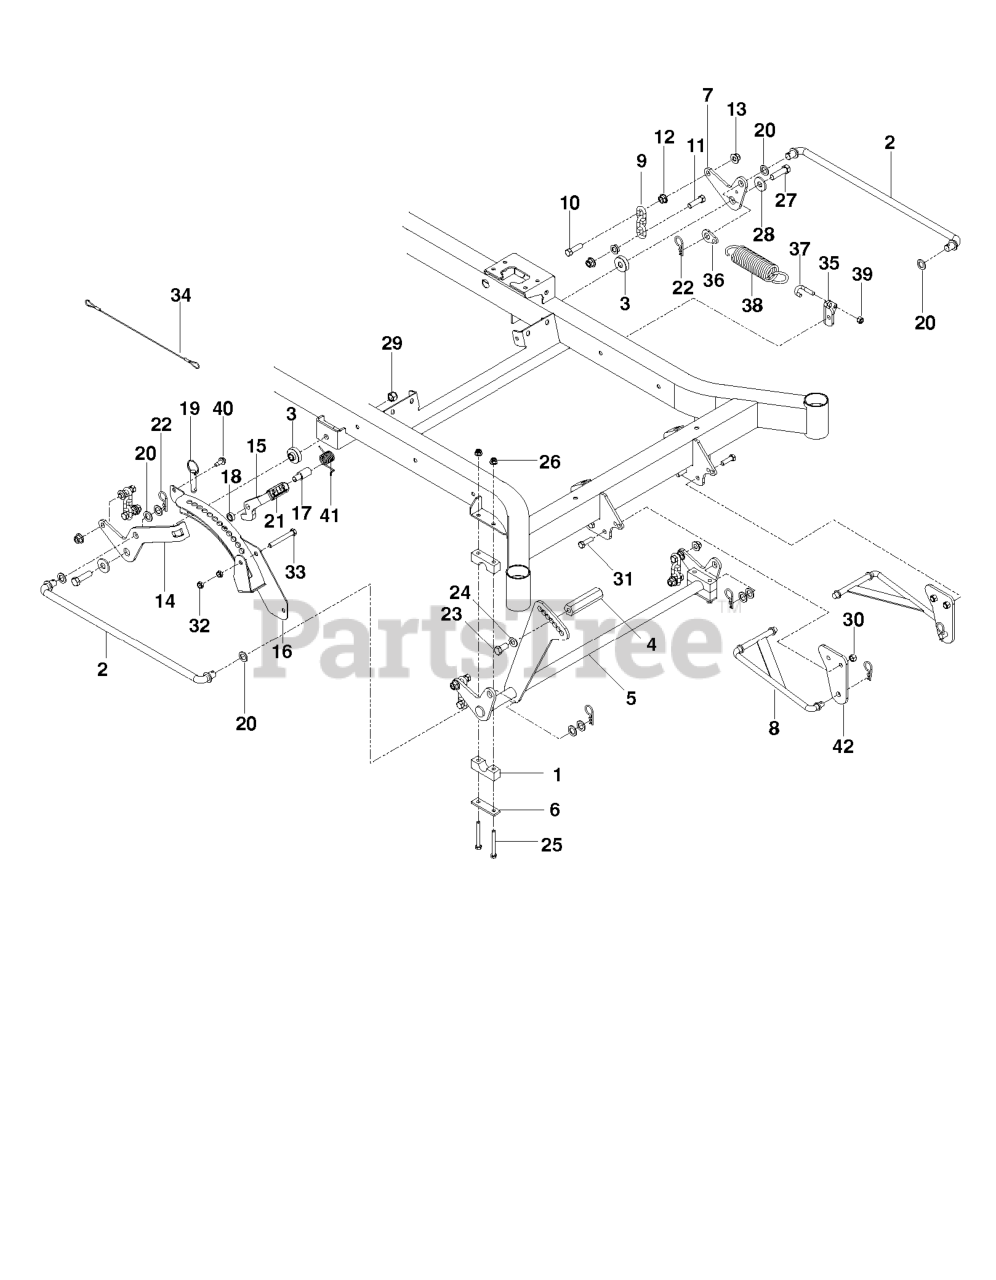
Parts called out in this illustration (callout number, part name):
1	PILLOW BLOCK
2	CROSS LINK
3	IDLER SPACER
4	PEDAL, FOOT, HEX
5	SHAFT, FRONT-LIFT
6	REINFORCEMENT BAR
7	BELLCRANK, RR, LIFT
8	STRUT LINKAGE
9	LIFT CHAIN - 3 LINK
10	HCS 7/16C X 1 1/2
11	HCS 7/16 - 14 X 1 3/4
12	NUT 7/16C WHIZ
13	NUT 7/16-14 HEX WHIZ LK
14	BELLCRANK, RR, RT
15	LATCH, TRANSPORT
16	HEIGHT, ADJUST, DECK
17	PIVOT, LATCH, TRANSPORT
18	SPACER, .3
19	PIN, 1/2 X 1 1/2, DETENT RING
21	GRIP, TRANSPORT-RELEASE
22	PIN, COTTER 1 3/4
23	HHCS 1/2-13 X 1
24	WASHER, 7/16 DISC SPRING
25	HCS 5/16C X 2-3/4
26	5/16-18 NYLOC FLANGE NUT
27	HCS 1/2-13 X 1 3/4 GR 8
28	WASH USS FLAT 1/2
29	NUT 1/2-13 HEX NYLOC ZD
30	NUT 3/8-16 NYLOC
31	HCS 3/8C X 1 1/4 GR5
32	NUT HEX 3/8-16 NYLON, THIN
33	HCS 3/8C X 3
35	MOUNT, SPRING
36	TAB, SPRING
39	NUT 5/16 NYLOC
40	BOLT 5/16-18 X 3/4
41	SPRING, TORSION
42	MOUNT, STRUT
